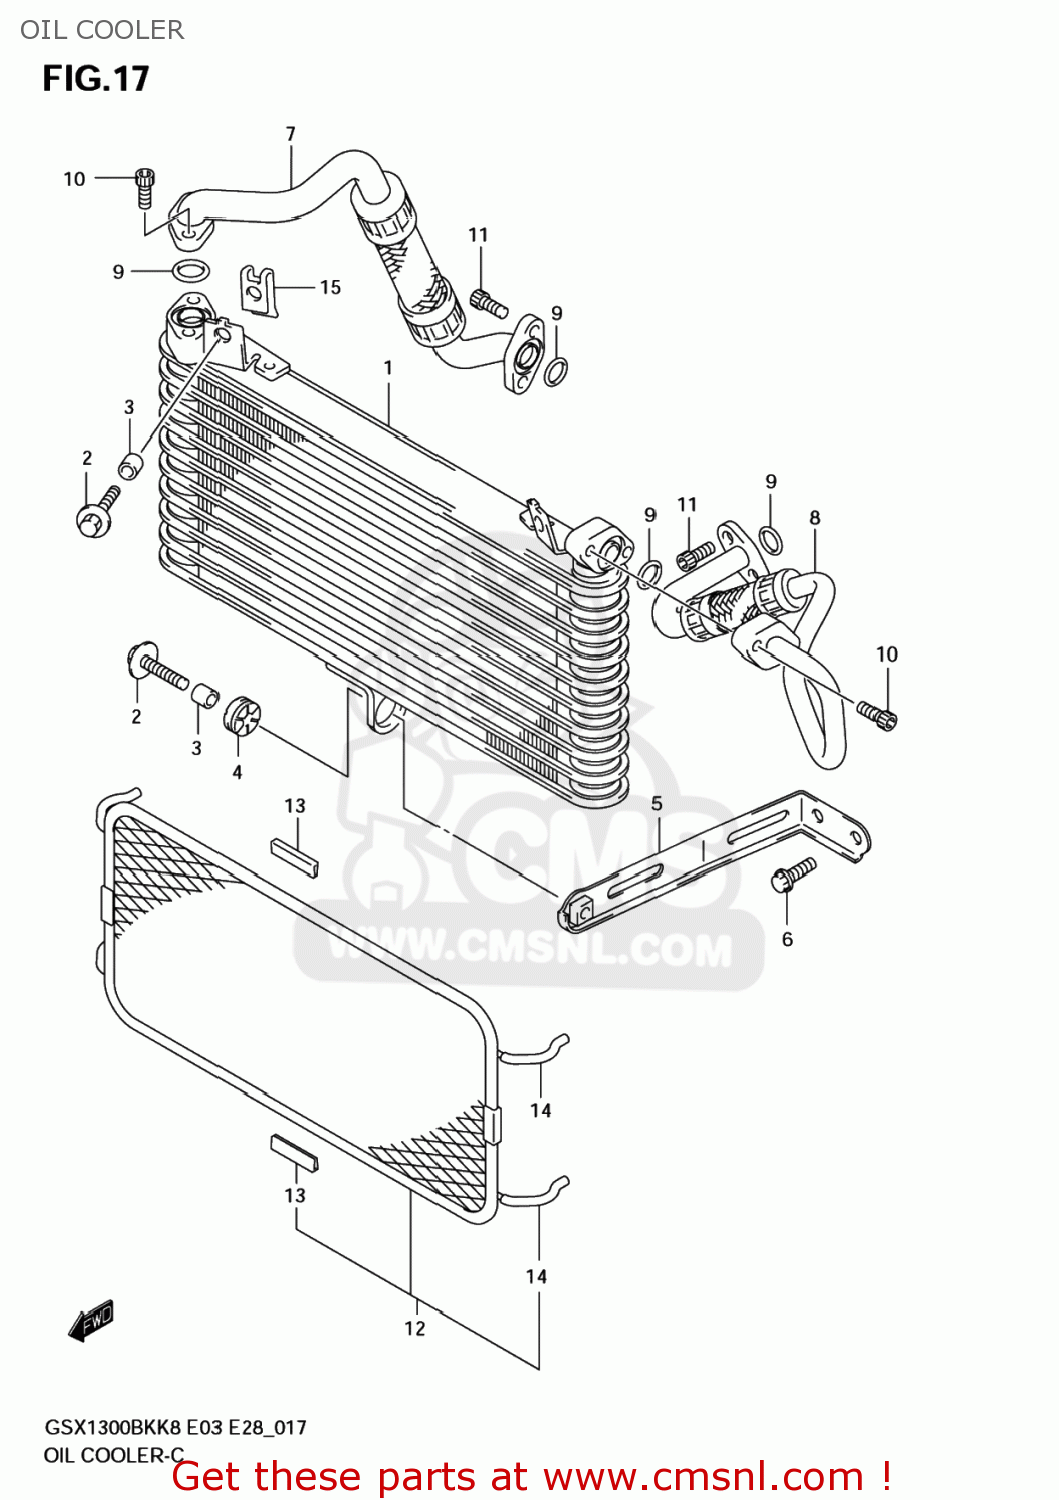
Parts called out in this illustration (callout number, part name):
1	COOLER ASSY,OIL
2	BOLT(6X25)
3	SPACER(6.5X10X12)
4	CUSHION
5	BRACKET,OIL COOLER
6	BOLT
7	HOSE,OIL COOLER,R
8	HOSE,OIL COOLER,L
9	O RING(D:2.4,ID:16)
10	BOLT(6X20)
11	BOLT(6X16)
12	GUARD,OIL COOLER
13	PROTECTOR,CTR
14	HOSE(3X5X600)
15	NUT,RADIATOR FAN
